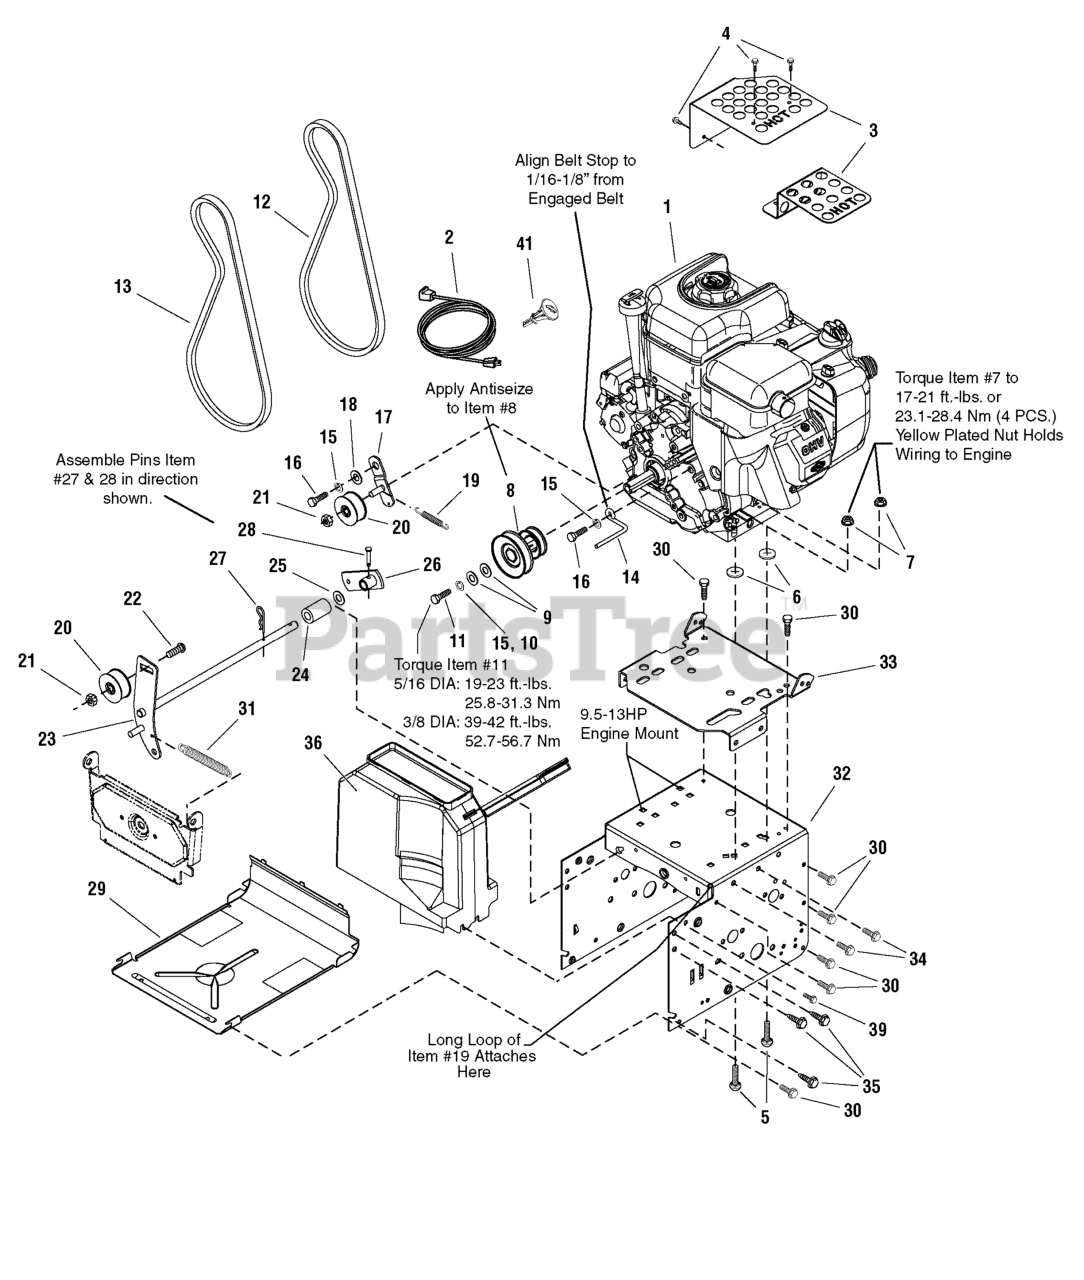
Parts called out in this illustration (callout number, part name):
1	ENGINE, 10.5HP B&S Powerbuilt *
1	ENGINE, 11.5HP B&S Intek *
1	ENGINE, 13HP B&S Intek *
2	CORD, Electric Start
3	GUARD, Muffler
4	SCREW, Hex Washer Head Taptite
5	CARRIAGE BOLT
6	NUT, Speed
7	NUT, Hex Flange, 5/16-18 Whiz Lock Small
8	PULLEY, Engine
9	WASHER, 3/8
10	LOCKWASHER, Spring 3/8
11	CAPSCREW, Hex Head, 3/8-24 x 1-1/4 G8
12	V-BELT, Drive
13	V-BELT, Auger
14	STOP, Belt
15	LOCKWASHER, Spring 5/16
16	CAPSCREW, Hex Head, 5/16-24 x 3/4 G5
17	IDLER BRACKET ASSEMBLY, Drive Belt
18	BUSHING, Idler Bracket
19	SPRING, Extension Idler
20	IDLER, Plastic Ball Bearing
21	NUT, Hex Jam, 3/8-16
22	CARRIAGE BOLT, 3/8-16 x 1-1/4
23	IDLER ASSEMBLY, Auger
24	SPACER, Auger Idler
25	WASHER, 1/2
26	BRACKET & HUB ASSEMBLY, Spring
27	PIN, Hair
28	PIN, Clevis
29	PANEL, Bottom
30	SCREW, Hex Washer Head Taptite, 1/4-20 x 5/8
31	SPRING, Extension Auger Idler
32	FRAME BOX
33	PLATE, Engine Mount
34	SCREW, Hex Washer Head Taptite, 5/16-18 x 1/2
35	SCREW, Hex Washer Head Taptite, 5/16-18 x 3/4
36	COVER, Belt w/Toolbox Includes Decal
39	SCREW, Hex
